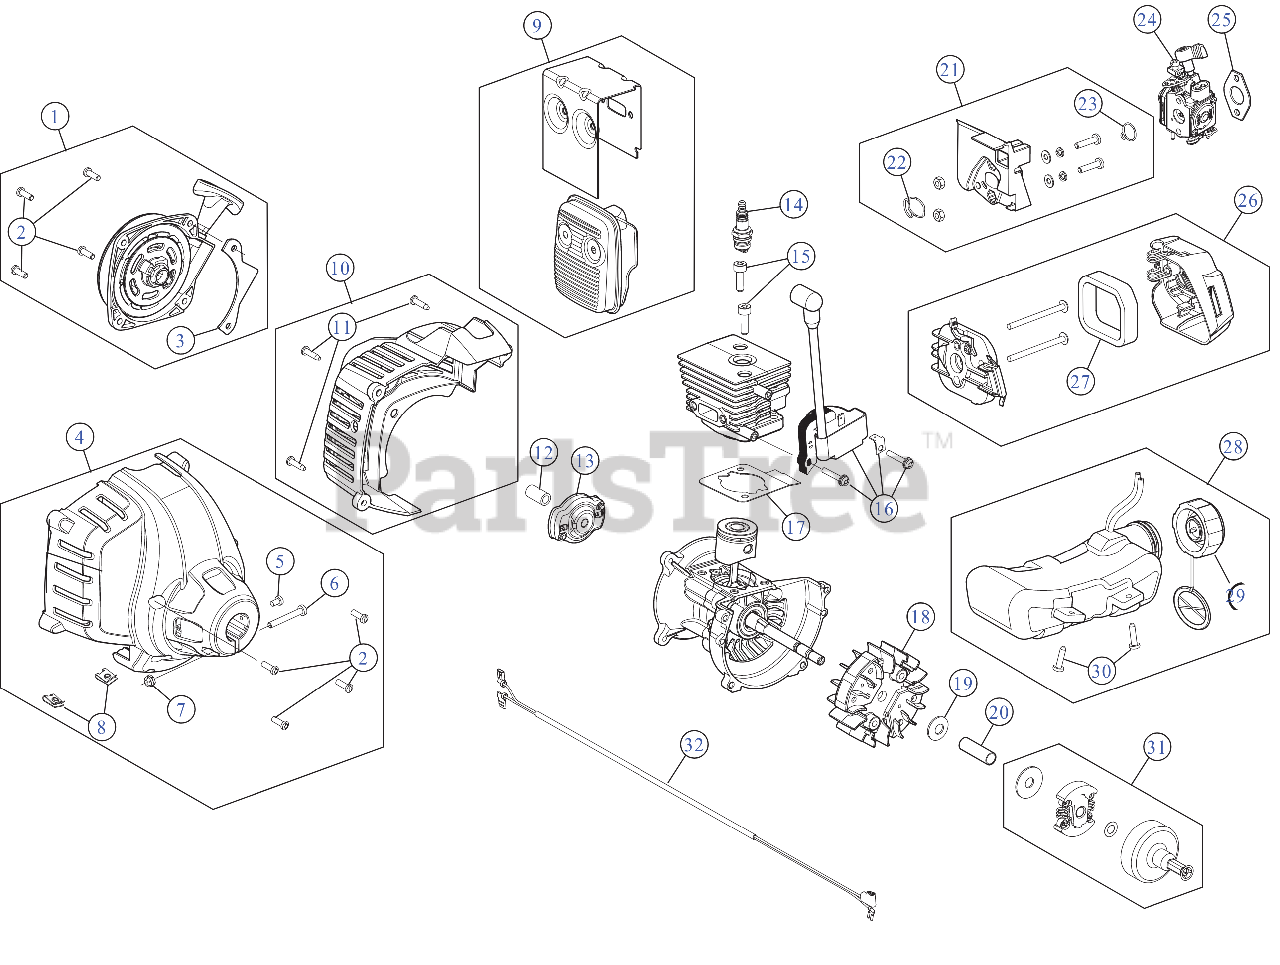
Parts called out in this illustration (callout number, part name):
1	STARTER ASSEMBLY RR
2	SCREW:10-32X.562:#8P
3	STARTER GUARD
4	CLUTCH COVER ASSEMBLY
5	SCREW, 8-32 x .312 P
6	SCREW
8	NUT, TINNERMAN U-T
9	MUFFLER ASSEMBLY
10	REAR ENGINE COVER
11	SCREW, #8-16X.750 PH
12	ELECTRIC START ADP
13	PAWL ASSEMBLY AC5
14	SPARK PLUG 14MM
15	SCREW 1/4 x 20 x .8125
16	MODULE 27CC DIG
17	GASKET CYL
18	FLYWHEEL ASSEMBLY 27CC
19	BELL WASHER
21	INTAKE ASSEMBLY
24	CARBURETOR
25	GASKET CARB
26	AIR CLEANER ASSEMBLY
27	AIR FILTER
28	FUEL TANK ASSEMBLY
30	SCREW:10-6 x .75
31	SMALL CLUTCH ASSEMBLY W/SMALL DRUM
32	LEAD WIRES
